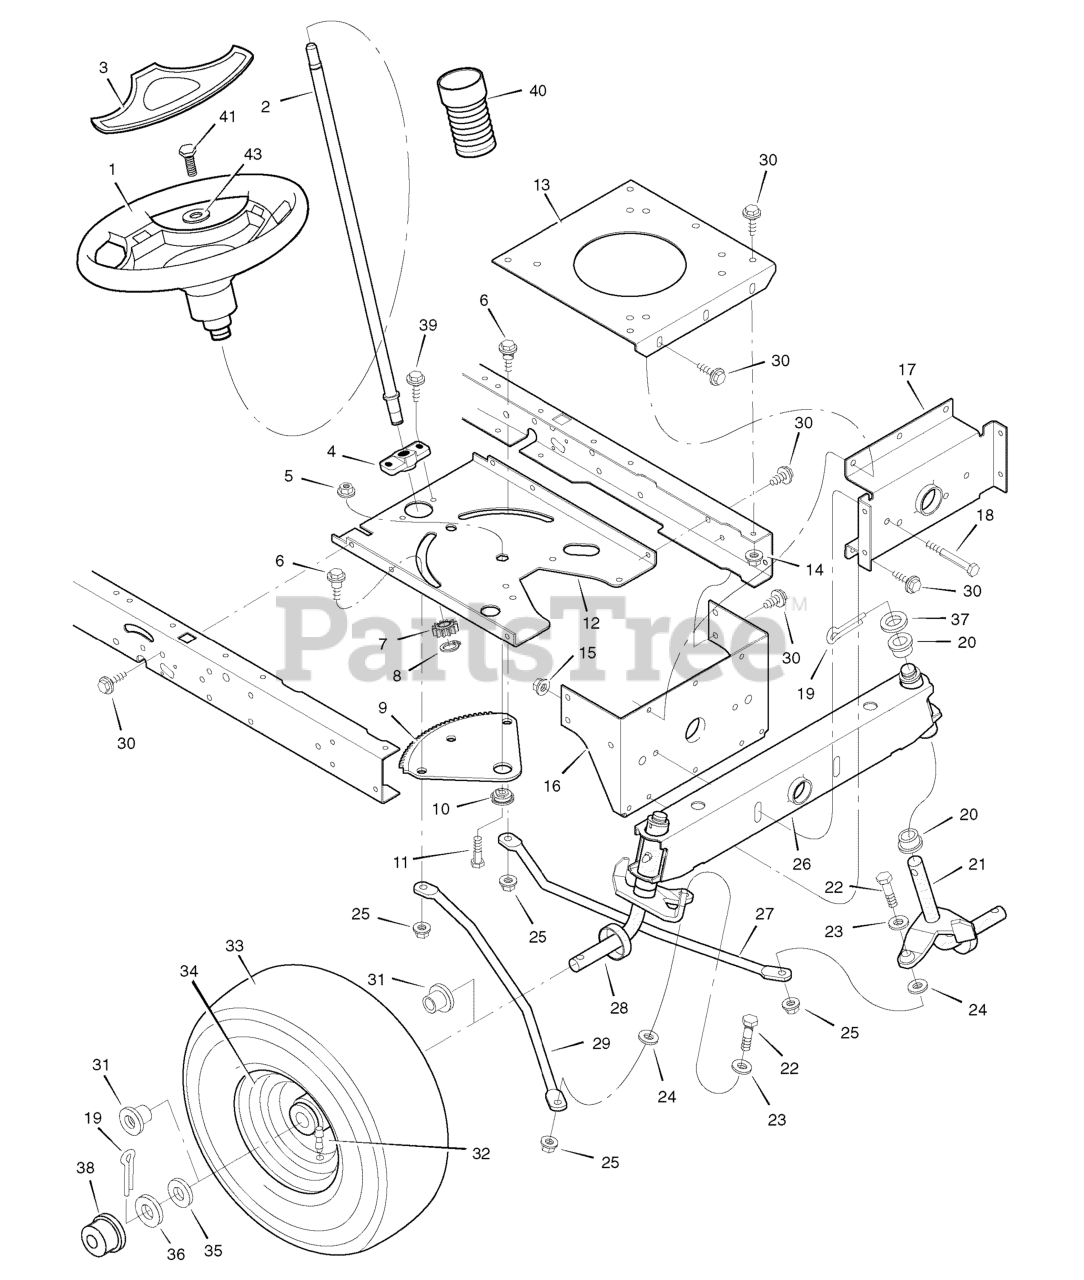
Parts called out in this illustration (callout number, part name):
1	Wheel, Steering
2	Post, Steering
3	Cover, Steering Wheel
4	Bearing
5	Nut, Flange
6	Bolt, Shoulder
7	GEAR, Pinion
8	Ring, Snap
9	Gear, Sector
10	Bearing
11	CAPSCREW, Hex Head, 5/16-18 x 1
12	Plate, Steering
13	Plate, Engine
14	Nut, Flange
15	Nut, Flange
16	Bracket, Hanger
17	Axle, Hanger
19	Pin, Cotter
20	Bearing
21	Spindle Assembly, Left
22	Bolt
23	Washer
24	Washer
25	Nut, Flange
26	Axle Assembly
27	Drag Link, Left
28	Spindle Assembly, Right
29	Drag Link, Right
31	Bearing, Wheel
32	Stem, Valve
34	Wheel and Tire Assembly
38	Hub Cap
40	Bellows
41	Screw, Hex
43	Washer
